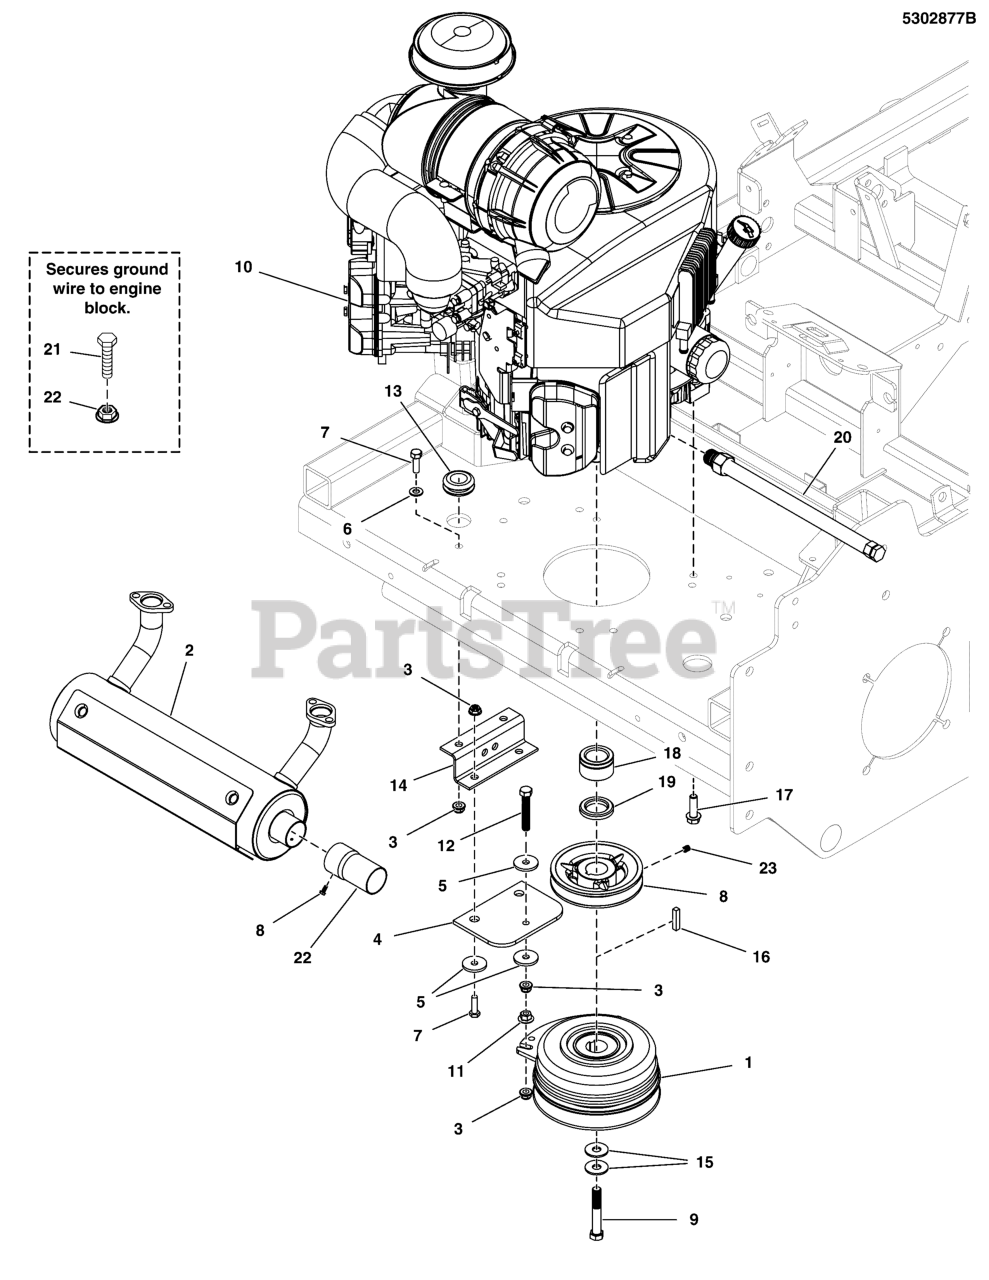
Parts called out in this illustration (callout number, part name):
1	CLUTCH, WARNER, 200 ft lbs - 1.13"
2	MUFFLER, 27HP KAWASAKI, 5" CAN
3	NUT, 5/16-18 HEX NYLOCK FLANGE
4	CLUTCH ANCHOR PAD
5	WASHER, .34 X 1.25 X 10 GA
6	WASHER, 5/16" SAE
7	BOLT, 5/16-18 X 1 GD5 CZ
8	PULLEY, 4.75 OD X 1-1/8 BORE, BC-48
9	BOLT, CRANKSHAFT,7/16-20X2-3/4, GD8
10	ENGINE, 26HP KAWA, FX801V
11	NUT, 5/16-18 HEX SERRATED FLANGE (LARGE)
12	BOLT, 5/16-18 X 2-1/4 TFL, GD5 YZ
13	GROMMET, 7/8"ID, 1/4" THICK STK
14	ANCHOR, CLUTCH - BLK
15	BELLEVILLE WASHER 1.1875 X .442 X .089
16	KEY, 1/4 SQ X 1-1/4
17	BOLT, 3/8-16 X 1-1/4, SF, PLT W/PATCH
18	SPACER, 1.13 X 1.75 X 1.03, CZ
19	SPACER, 1.13 X 1.75 X .25
20	HOSE, OIL DRAIN, M20 X 2.5
21	BOLT, M8-1.25 X 20MM GD8.8
22	NUT, M8-1.25 SERR. FLANGE, CZ
23	SET SCREW, 5/16-18 X 3/8, KNURL, W/PATCH
